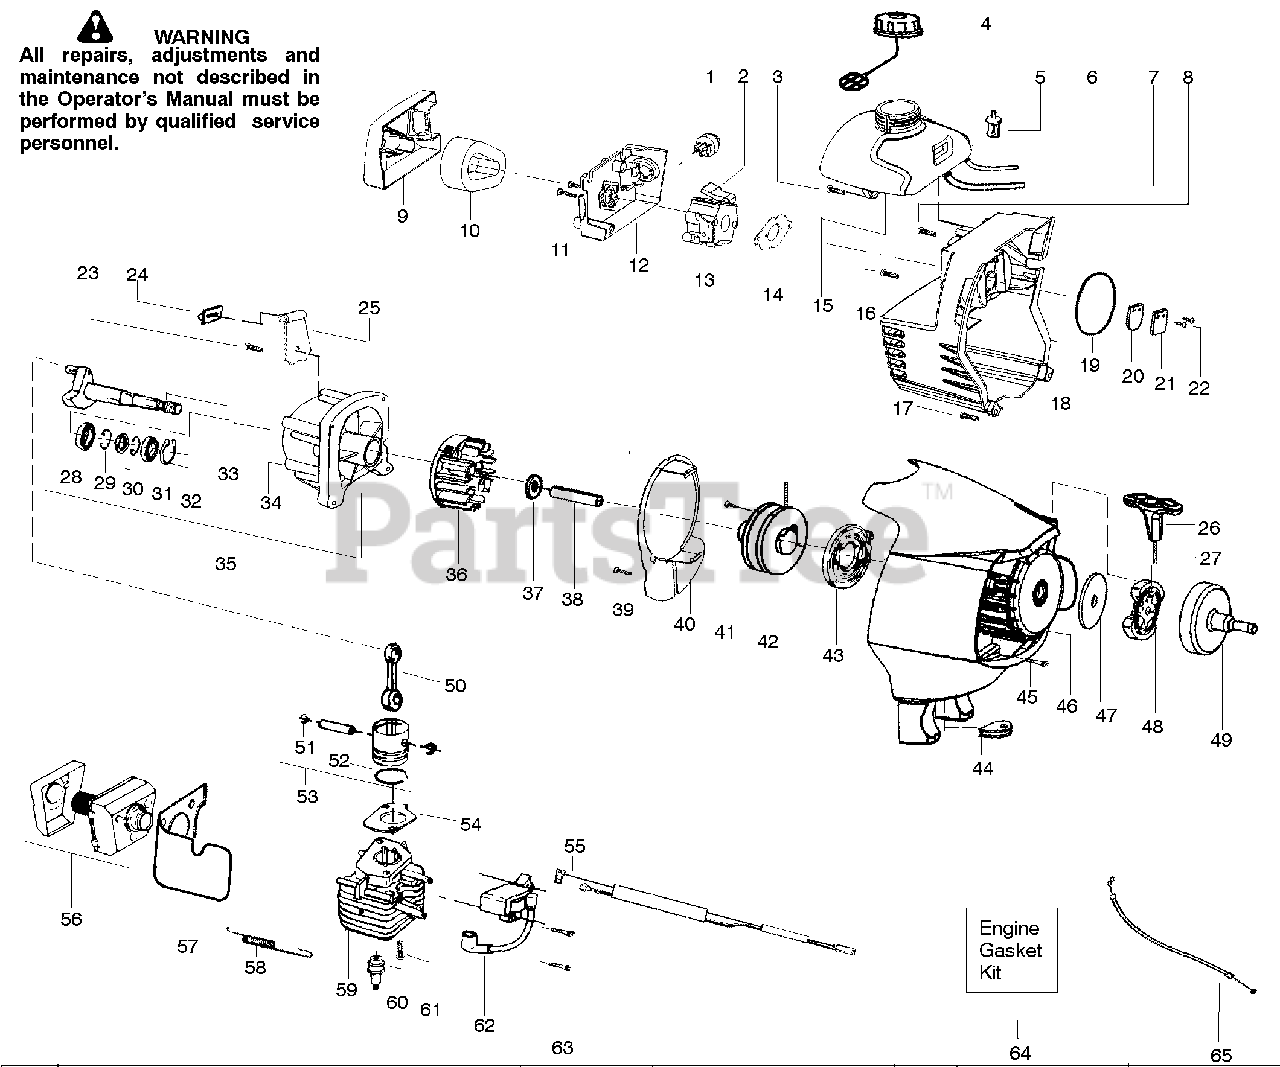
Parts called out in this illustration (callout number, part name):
2	Kit-Choke Lever
4	Cap-Fuel w/ret.
5	Assy-Fuel pickup
6	Kit-Fuel line
7	Kit-Fuel/Purge line
9	Cover-Air box
13	Assy-Carb(WT628)
14	Gasket-Carb.(kit)
15	Assy-Fuel Tank
16	Screw-Crankcase
19	O-ring-Shroud (kit)
22	Screw-Reed stop
23	Screw-Retainer
24	Isolator-Tank
26	Handle-Starter
28	Bearing-Inner
31	Bearing-Outer
32	Ret.-Crankshaft
33	Assy-Crankshaft
34	Assy-Crankcase
35	Assy-C'case/C'shaft
36	Assy-Flywheel
40	Plate-Baffle
42	Kit-Pulley
43	Spring-Starter
45	Screw-F/hsg.
46	Assy.-Fan Housing
47	Washer-Clutch
49	Drum-Clutch
50	Assy-Conn. Rod
51	Ret.-Piston pin
53	Kit-Piston
54	Gasket-Cylinder(kit)
55	Assy-Leadwire
58	Spring-Muffler
59	Cylinder
60	Plug-Spark(RCJ-6Y)
61	Bolt-Cyl. 1/4-20"
62	Module-Ignition
64	Kit-Gasket
65	Assy-Throttle cable
